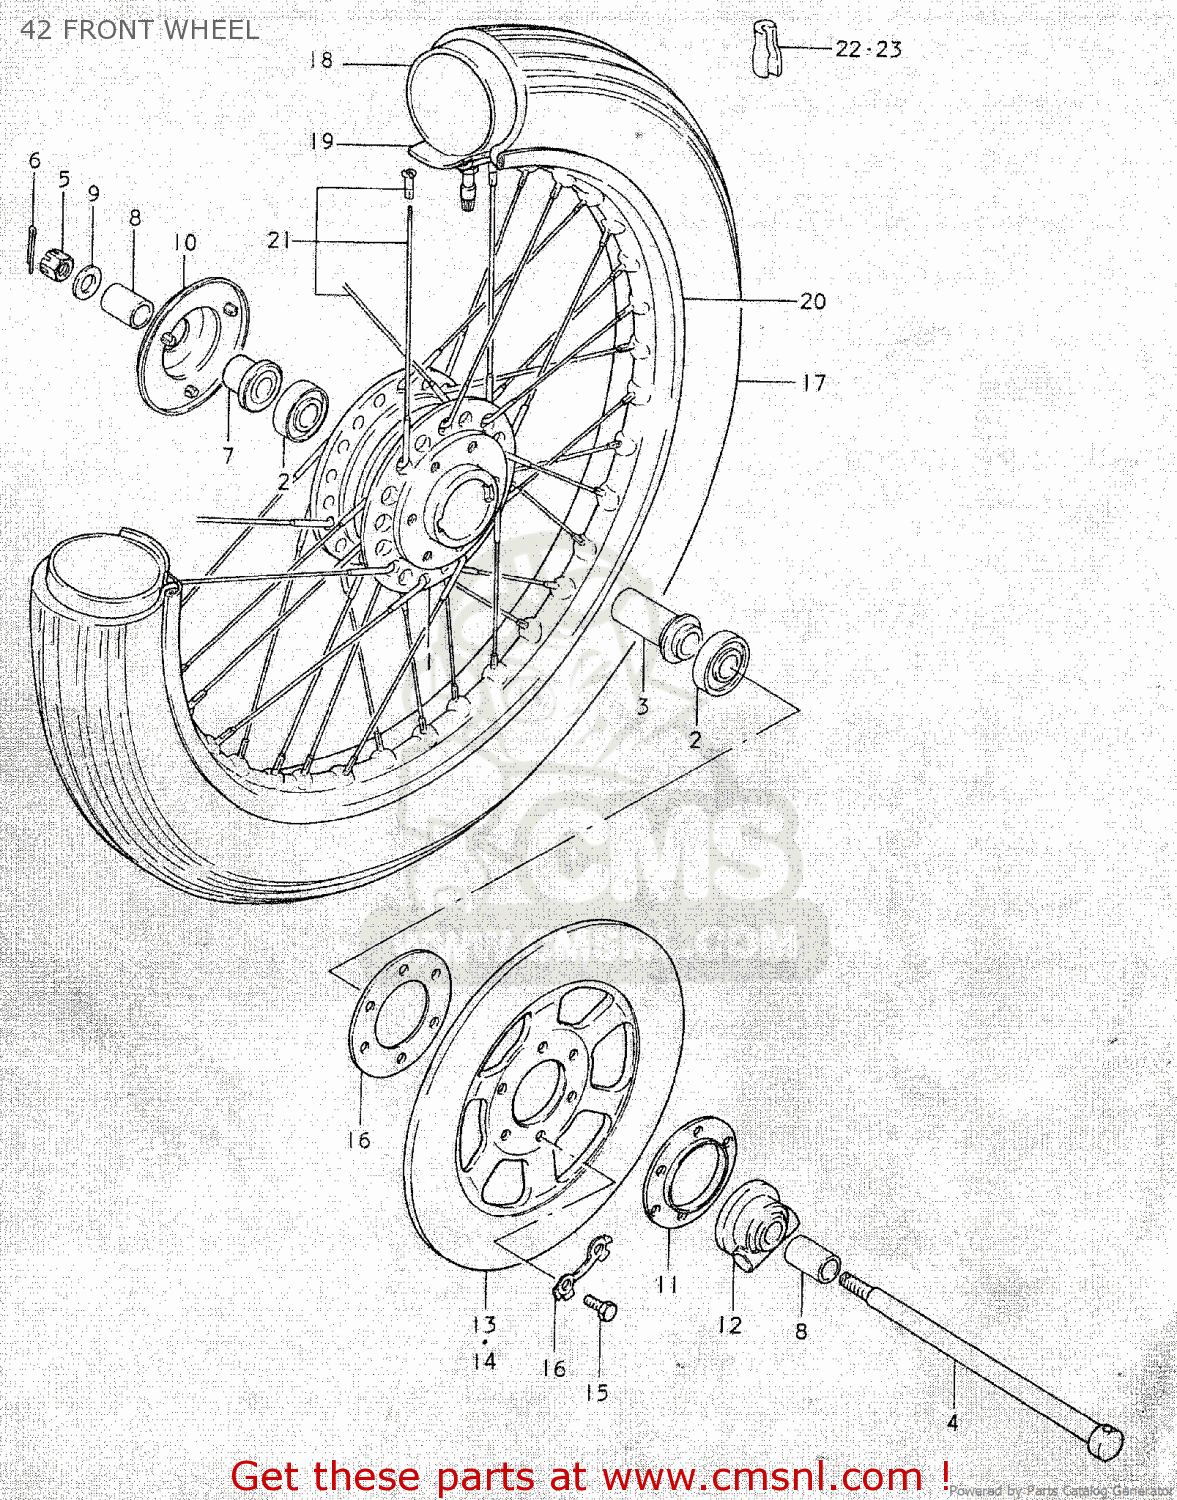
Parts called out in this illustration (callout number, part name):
1	HUB,FRONT WHEEL
2	BEARING
3	SPACER,FR HUB BEARING
4	AXLE,FRONT
5	NUT 12MM
6	COTTER PIN
7	SPACER,FRONT AXLE,RIGHT
8	SPACER(15X22X30)
9	WASHER
10	COVER,FR HUB,R
11	DUST SEAL,SPEEDOMETER GEAR BOX
12	BOX ASSEMBLY,SPEEDOMETER GEAR
13	DISC,BRAKE
15	BOLT(8X25)
16	WASHER
17	TIRE,FRONT
18	TUBE,INNER
19	PROTECTOR,WHL INR TUBE
20	RIM,FR WHEEL
21	SPOKE SET,FRONT
22	BALANCER,WHEEL (B)
23	BALANCER,WHEEL (30G)
